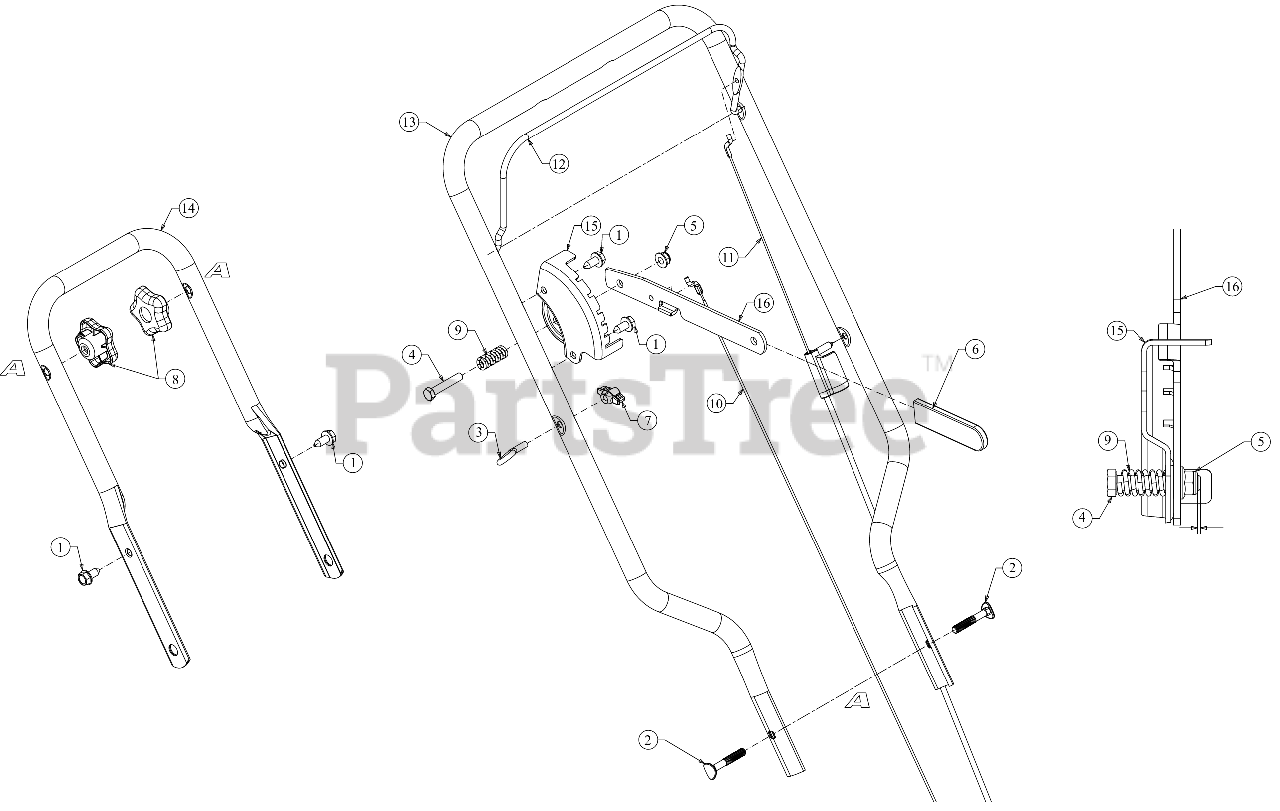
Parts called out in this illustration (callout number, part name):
1	SCREW 5/16-12 x .750
2	SCREW 5/16-18 x 2.0
3	EYEBOLT 1/4-20
4	SCREW 5/16-18 x 1.75 GR5
5	FLANGE LOCK NUT 5/16-18
7	HANDLE KNOB
8	STAR KNOB 5/16-18
10	WHEEL ADJUSTMENT CABLE
11	CONTROL CABLE 31"
12	BLADE CONTROL BAIL
